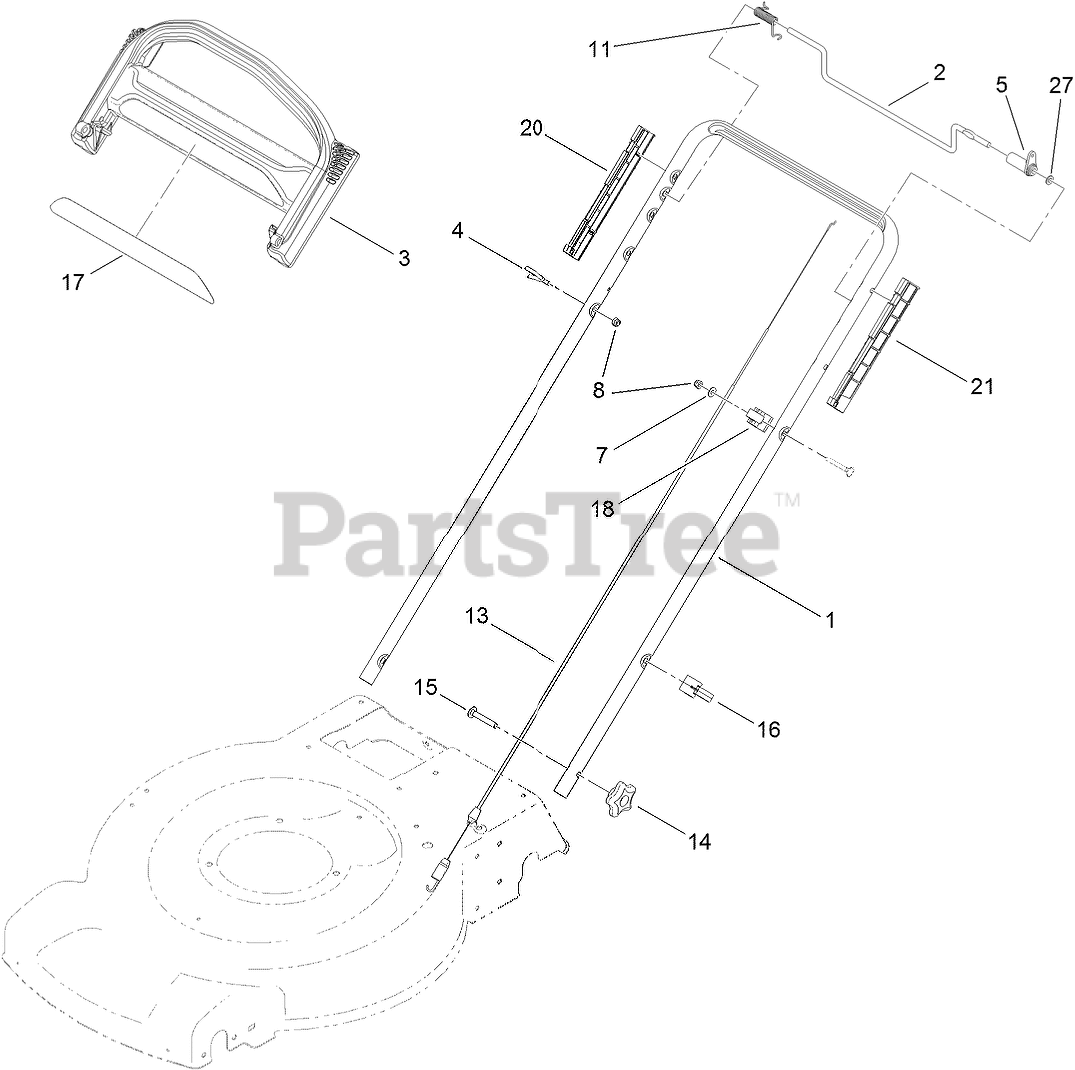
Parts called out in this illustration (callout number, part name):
2	BAR-CONTROL, TRACTION
3	HANDLE-CONTROL
4	GUIDE-ROPE
5	LEVER-TRACTION
7	WASHER-FLAT
8	NUT-LOCK, NI
11	Spring-Torsion
13	CABLE-TRACTION
14	KNOB-HANDLE
15	Screw-CARR
16	GUIDE-CABLE
18	ANCHOR-CABLE
20	GUIDE-RH
21	GUIDE-LH
27	WASHER-PLAIN
